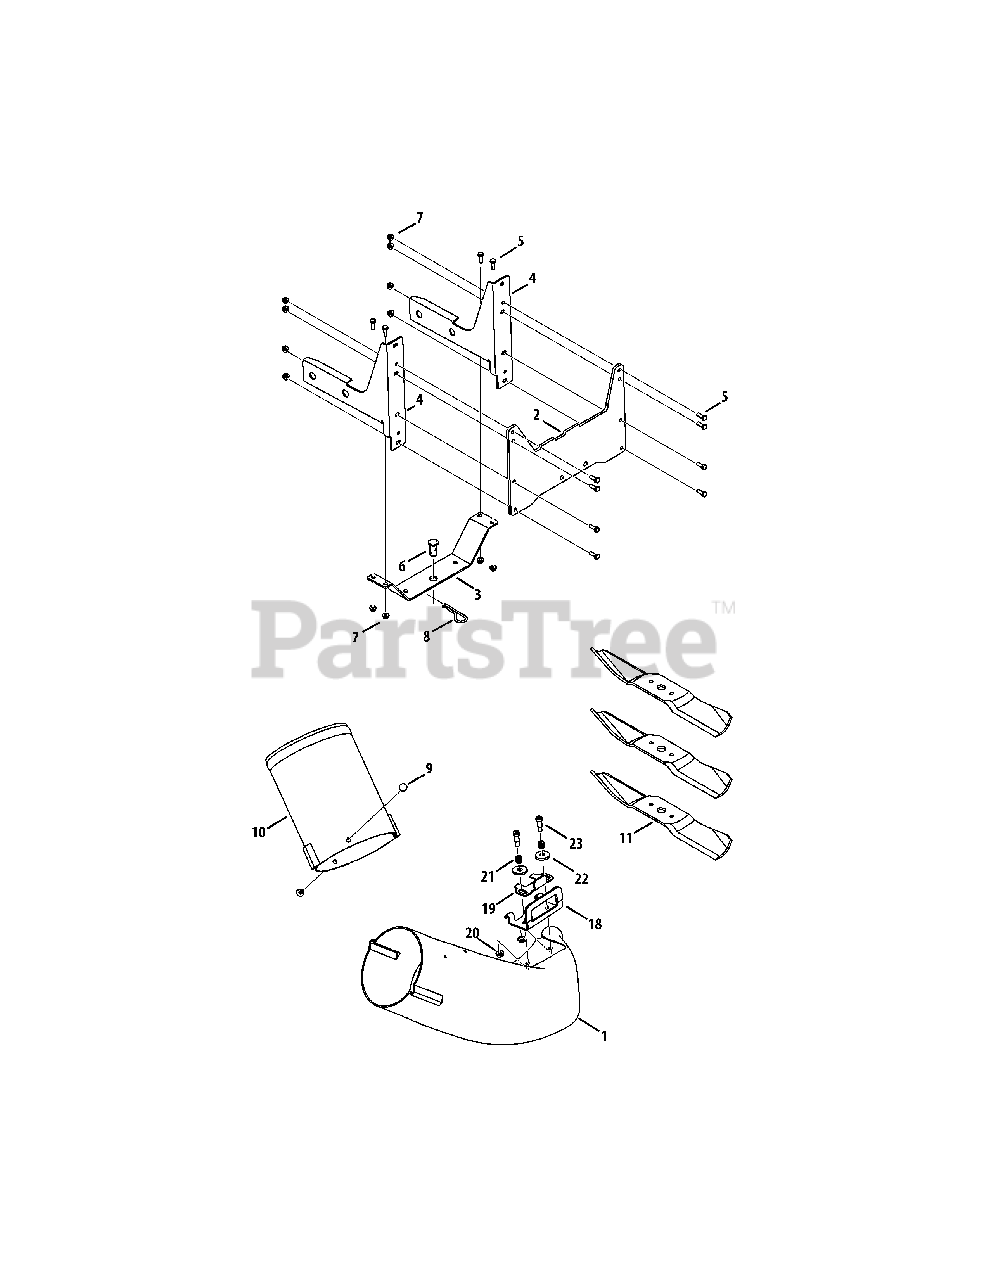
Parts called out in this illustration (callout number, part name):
1	Chute Discharge Elbow, 44" Deck
2	Bagger Mounting Plate
4	Catcher Support Bracket
5	Hex Head Screw, 1/4-20 x .75
6	Clevis Pin, .62" Dia.
7	Flange Lock Nut, 1/4-20
8	Internal Cotter Pin, .148 x 3.00
9	Ratchet Clip
10	Bagger Chute Adapter
11	Blades, 15.94 x 2.5 x .2
18	Chute Bracket, 44" Deck
19	Bag Latch
20	HEX FLANGE NUT
21	Compression Spring, .50 OD x .50 Lg.
22	Flat Washer, .406 x 1.25 x .157
23	Shoulder Screw, 3/8 x .625; 5/16-18
